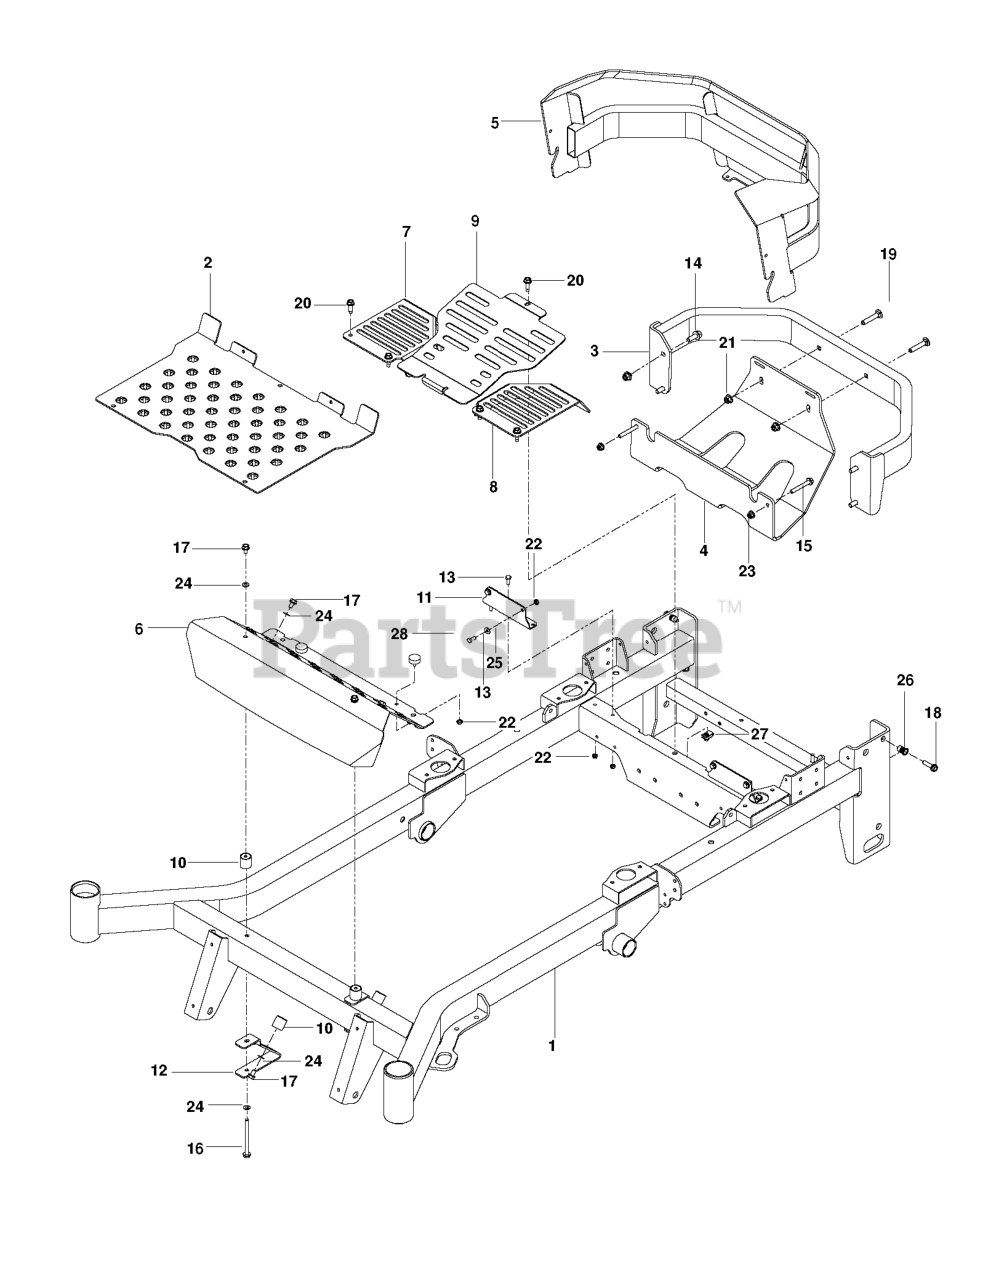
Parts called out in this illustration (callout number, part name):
1	FRAME W/DECALS, PZ
2	PLATE FLOOR PAN ORANGE
3	BUMPER, REAR, ORG
4	PLATE.SKID.GRAY
5	GUARD.REAR.GRAY.ZTR
6	PLATE, FOOT REST, OR
7	COVER, FAN RT BLK
8	COVER, FAN LT BLK
9	COVER, CENTER BLK
10	MOUNT, F/F INSERT
11	MOUNT TANK BLK
12	BRACKET, REST MOUNT
13	HCS 1/4C X 5/8
14	HHFS 3/8-16 X 1 GRD 5 ZD
15	HHFS 5/16-18 X 2.25 GD 5
16	HHFS 5/16-18 X 3 3/4
17	SCR 5/16-18 X 1/2 SELFTAP ZN
18	HHFS 5/16-18 X 1.25 TPBLT GD 5
19	RHSNB 3/8C X 2
20	RP BLT 5/16-18 X 1 THRD FORM D
21	NUT 3/8-16 HEX FLG NYLOC ZD
22	JAM NUT 1/4C (2 2 PW01)
23	5/16-18 NYLOC FLANGE NUT
24	WASH 5/16 DISC SPRING ZD
25	WASHER 1/4 SAE
26	NUTSERT 5/16-18 THICK GRIP
27	U-CLIP 5/16-18 NUT RETAINER
28	BUMPER, 1/4-20 STUD, 1/4
